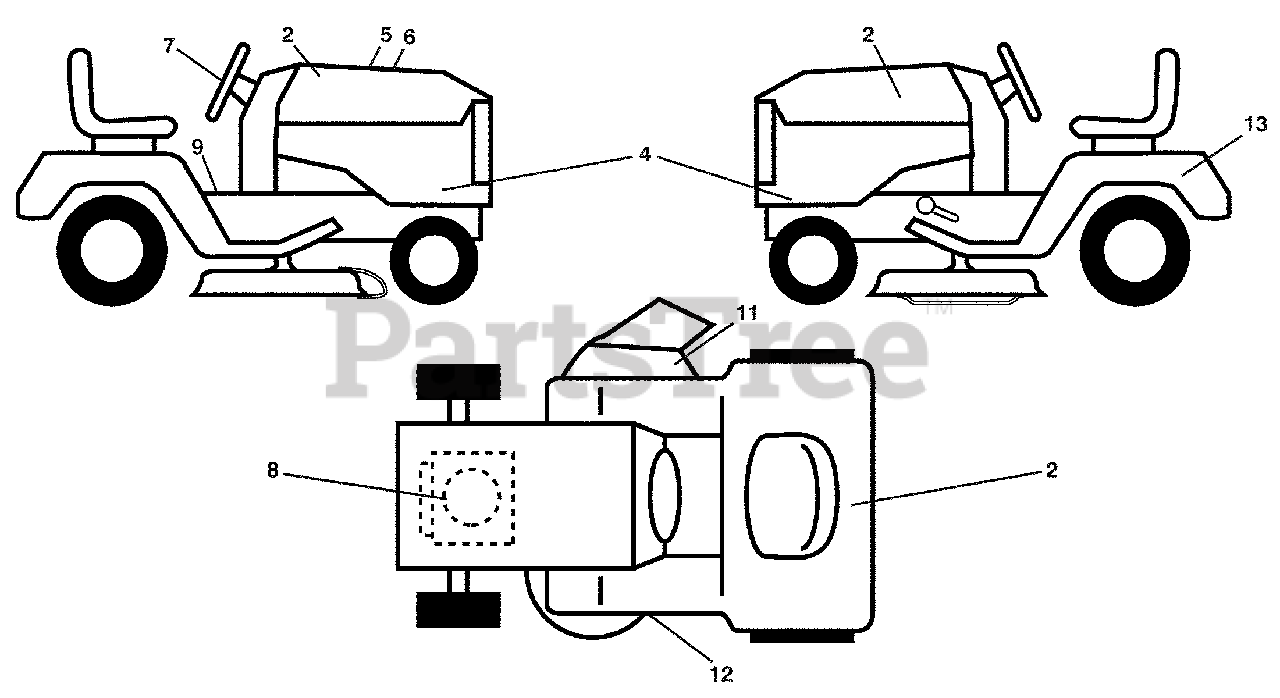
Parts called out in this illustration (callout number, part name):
2	Decal, Hood
4	Decal, Hood Panel
5	Decal, Customer Respons.
6	Decal, Replacement
7	Decal, Steering Wheel
8	Decal, Engine
9	Decal, Battery Dnge/Poi
11	Decal, Warning
12	Decal, Mower V-Belt Schematic
13	Decal, Fender Warn./Instructions
